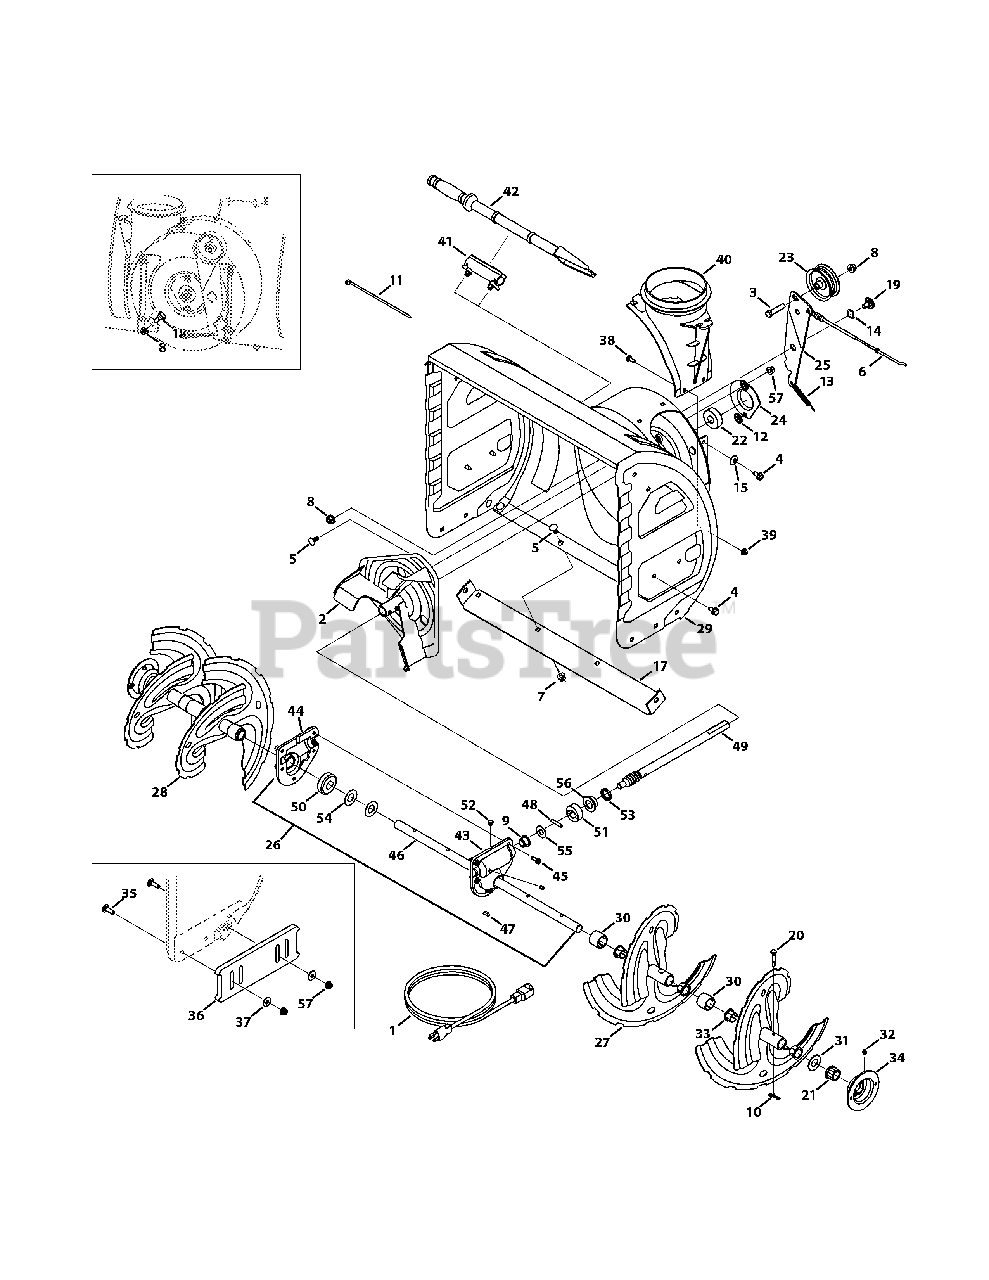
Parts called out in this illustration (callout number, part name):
1	Extension Cord
2	Impeller Assembly
3	Hex Bolt, 3/8-16 x 1.75
4	Screw, 5/16-18 x .750
5	Carriage Bolt, 5/16-18 x .750 (24")
5	Carriage. Bolt, 5/16-18 x .750 (26", 28")
6	Auger Clutch Cable
7	Flange Lock Nut, 5/16-18 (24")
7	Hex Nut, 5/16-18 (26", 28")
8	Flange Lock Nut, 3/8-16
9	Flange Bearing, .50 x .75 x .59
10	Bow Tie Cotter Pin
11	Cable Tie
12	Push-On Nut, .25 Dia.
13	Extension Spring, .38 OD x 4.59
14	Wave Washer, .625 x .885 x .0175
15	Bell Washer, .340 x .872 x .060
16	Bell Washer, .340 x .872 x .060
17	Stainless Steel, Shave Plate, 28"
17	Stainless Steel, Shave Plate, 26"
18	Shoulder Screw, 3/8-16 x .496 x .336
19	Shoulder Screw, 3/8-16 x .625 x .17
21	Hex Flange Bearing
22	Flange Ball Bearing, .75 x 1.85
23	Flat Idler Pulley
24	Bearing Housing
25	Auger Idler Bracket
26	Gearbox Assembly, Auger, 28"
26	Gearbox Assembly, Auger, 26"
26	Gearbox Assembly, Auger, 24"
27	Spiral Assembly - LH
28	Spiral Assembly - RH
29	Auger Housing, 28"
29	Auger Housing, 26"
29	Auger Housing, 24"
30	Spacer, 1.25 x .75 x 1.00
31	Flat Washer, .76 x 1.49 x .06
32	Drive Lube Fitting
33	Flange Bushing, .800 x .910
34	Bearing Housing
35	Spacer, Carriage, 5/16-18 x 1.00
36	Deluxe Slide Shoe
37	Washer, Flat, .349 x .879 x .063
38	Carriage Screw, 1/4-20 x 0.75
39	Flange Lock Nut, 1/4-20
40	Chute Adapter
41	Clean-out Tool Mtg. Bracket
42	Clean-Out Tool
43	Housing Assembly - RH
44	Housing Assembly - LH
45	Screw, 1/4-20 x 0.75
46	Axle, Auger, 28"
46	Axle, Auger, 26"
46	Axle, Auger, 24"
47	Hi-Pro Key
48	Dowel Pin, .25OD x 1.25
49	Worm Shaft
50	Worm Gear, 20T, (28")
50	Worm Gear, 20T, (24"), (26")
51	Thrust Collar
52	Plug, 1/4 x .437
53	Oil Seal, .75 x 1.131 x .188
54	Flat Washer, .76 x 1.5
55	Flat Washer, .51 x 1.12 x .06
56	Flange Bearing, .75 x 1.00 x .59
57	Flange Lock Nut
